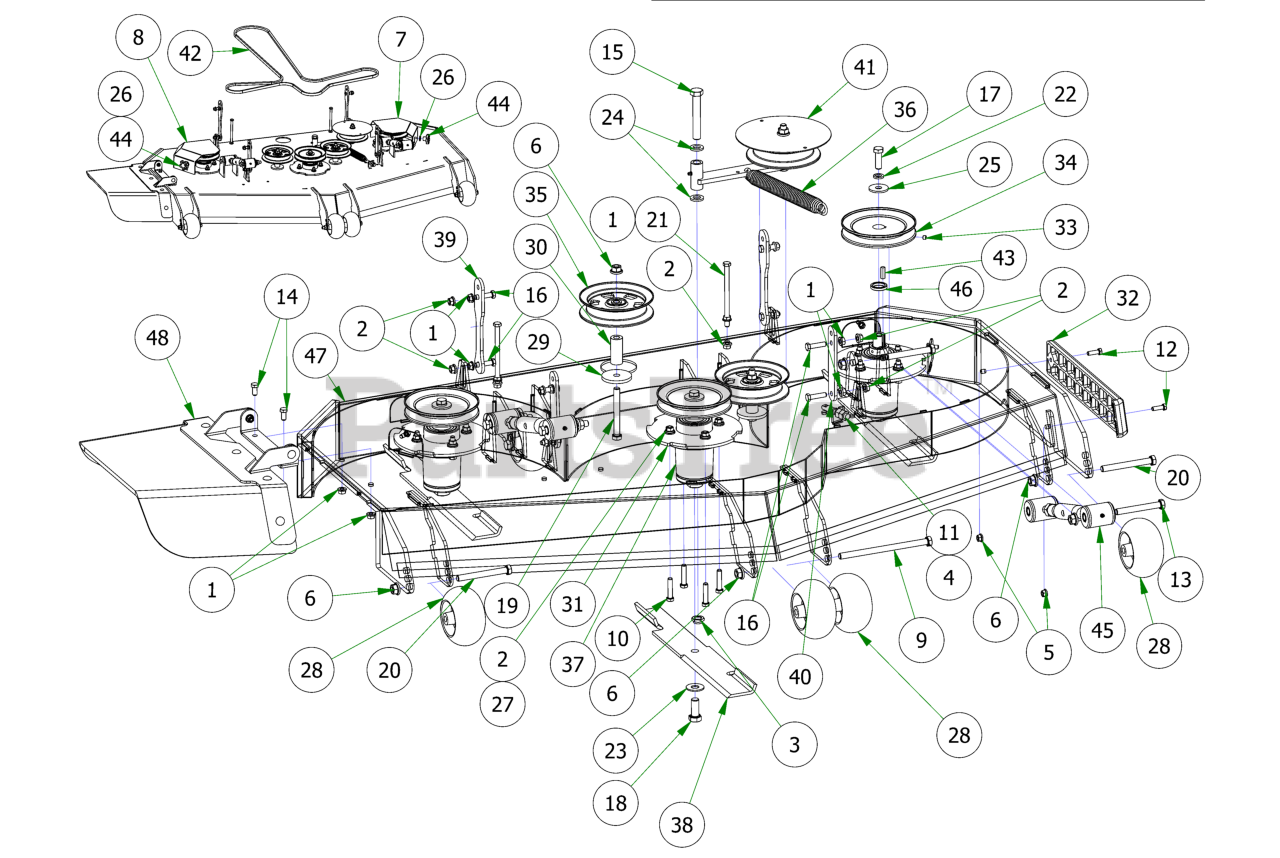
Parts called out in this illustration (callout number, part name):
1	3/8-16 HEX SERRATED FLANGE NUT HARD/ZINC
2	3/8-16 NYLON INSERT FLANGE LOCKNUT (GR.F) ZINC
3	5/8-11 NYLON INSERT JAM LOCKNUT ZINC
4	1/2-13 HEX NUT ZINC
5	5/16-18 NYLON INSERT FLANGE LOCKNUT ZINC
6	1/2-13 NYLON INSERT FLANGE LOCKNUT ZINC
7	2019 Stand On 54" Pulley Cover Trim
8	2019 Stand On 54" Pulley Cover Discharge
9	1/2-13 X 8 HEX CAP SCREW GR 5 ZINC
10	3/8-16 X 1-3/4 HEX C/S (GR.5) ZC
11	All Thread
12	5/16-18 X 1 HEX CAP SCREW (GR.5) ZINC
13	1/2-13 X 4 HEX CAP SCREW (GR.8) ZINC YELLOW
14	3/8-16 X 3/4 HEX CAP SCREW (GR.5) ZINC
15	5/8-11 X 4 HEX CAP SCREW (GR.8) ZINC YELLOW
16	3/8-16 X 1-1/2 HEX CAP SCREW (GR.5) ZINC
17	1/2-20 X 1-1/2 HEX CAP SCREW (GR.5) ZINC
18	5/8-18 X 1-1/2 HEX CAP SCREW (GR.8) ZINC YELLOW
19	1/2-13 X 4-1/4 HEX CAP SCREW (GR.5) ZINC
20	1/2-13 X 4-1/2 HEX CAP SCREW (GR.5) ZINC
21	3/8-16 X 5-1/2 HEX CAP SCREW (GR.5) ZINC
22	1/2 SPLIT LOCKWASHER (GR.8) ZINC/YELLOW
23	5/8 USS FLAT WASHER (1-3/4" OD) GR.8 ZINC YELLOW
24	.635 ID X 1.120 OD X .140 THICK FLAT WASHER NYLON
25	1/2 BELLEVILLE WASHER (1-5/8 OD X .140 THK) ZINC
26	.360 ID X .983 OD X .120 THICK FLAT WASHER NYLON BLACK
27	5/16 USS FLAT WASHER (7/8 OD) ZINC
28	2019 Deck Wheel
29	MZ Deck Idler Spacer
30	2019 Revolt Stationary Idle Spacer
31	Deck Spindle Support Plate
32	REVISED TRIM BUMPER_20180226
33	5/16-24 X 1/4 SOCKET SET SCREW (CUP PT) PLAIN
34	6 1/4" Drive Pulley
35	5-3/4 Idler Pulley
36	2019 Outlaw Gen2 Deck Spring
37	Spindle Assembly
38	61 inch Fusion Blade
39	2019 Stand-On Rear Deck Hanger
40	2019 Revolt Front Deck Hanger
41	2020 61 Revolt Deck Idler Assembly
43	1/4 X 1 SQ MACHINERY KEY 1018 STL PLN
44	5/16" Knob
45	Turnbuckle
46	Spacer, 1x1.375x.25
47	61" Revolt Deck Weldment-Bad Boy Orange
48	2019 Outlaw Gen2 Chute Assembly
